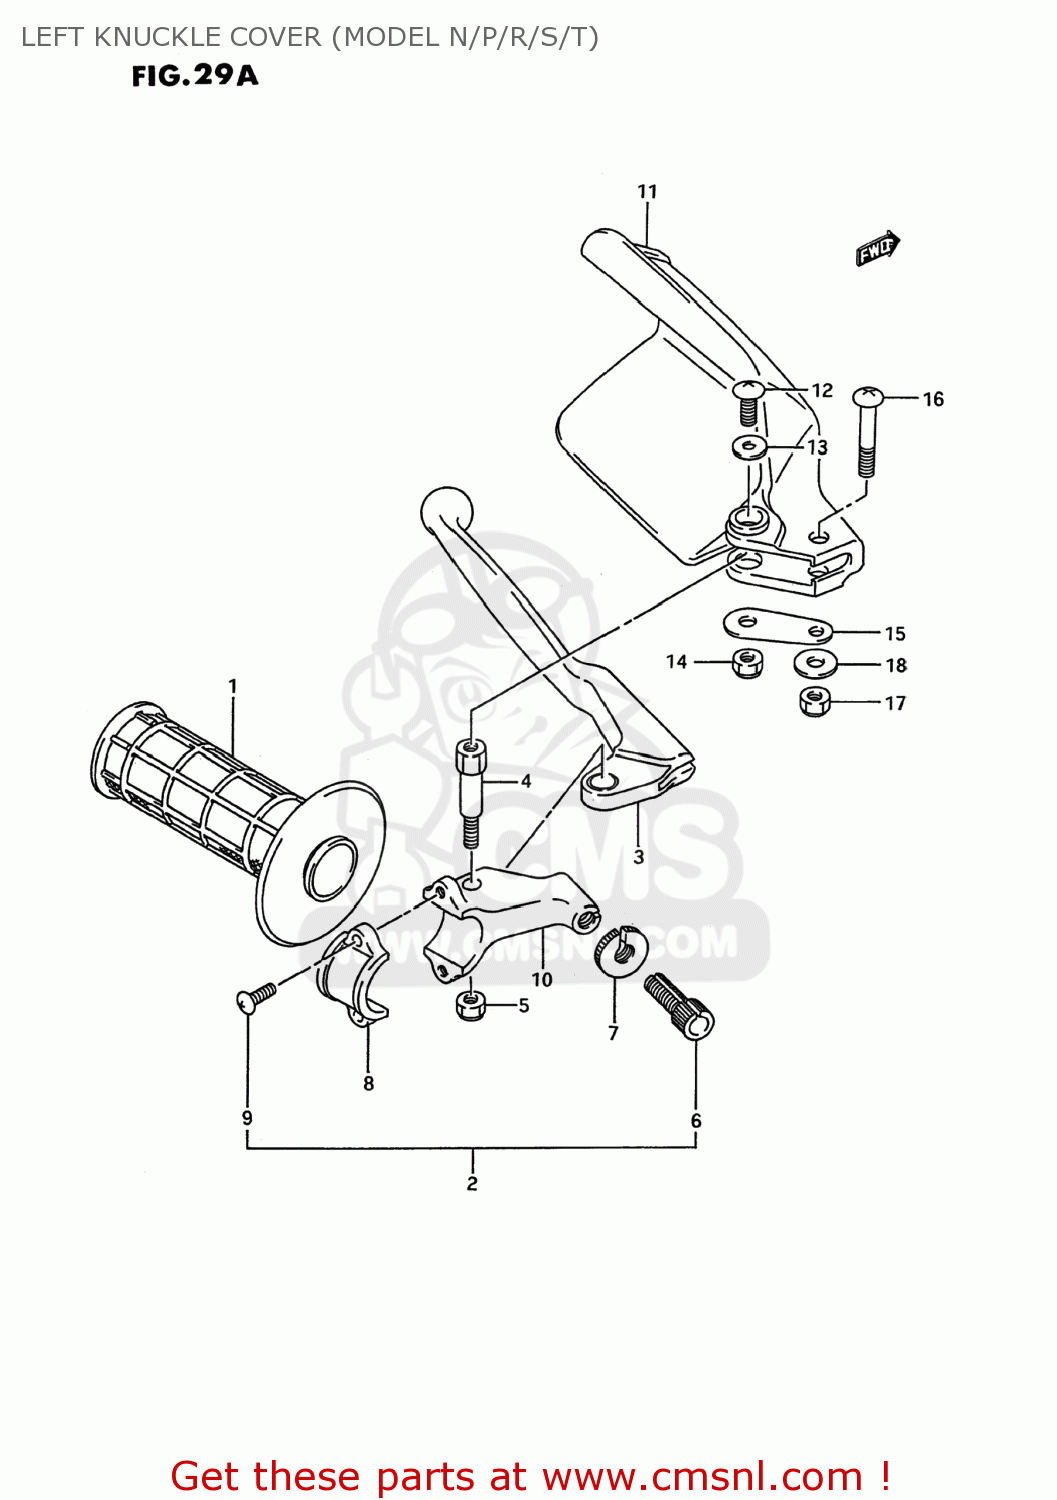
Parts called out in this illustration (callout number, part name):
1	GRIP,L
2	LEVER ASSY,CLUTCH
3	LEVER,CLUTCH
4	BOLT,LEVER SET
5	NUT 6MM
6	ADJUSTER,CABLE
7	NUT,LOCK
8	BRACKET,CLUTCH LEVER HOLDER
9	SCREW(5X14)
10	HOLDER,CLUTCH LEVER
11	COVER,KNUCKLE,L
12	SCREW
13	WASHER (5.5X16X1.2)
14	NUT 6MM
15	PLATE,KNUCKLE COVER,L LWR
16	SCREW(6X35)
17	NUT 6MM
18	WASHER (6.5X17X1.6)
